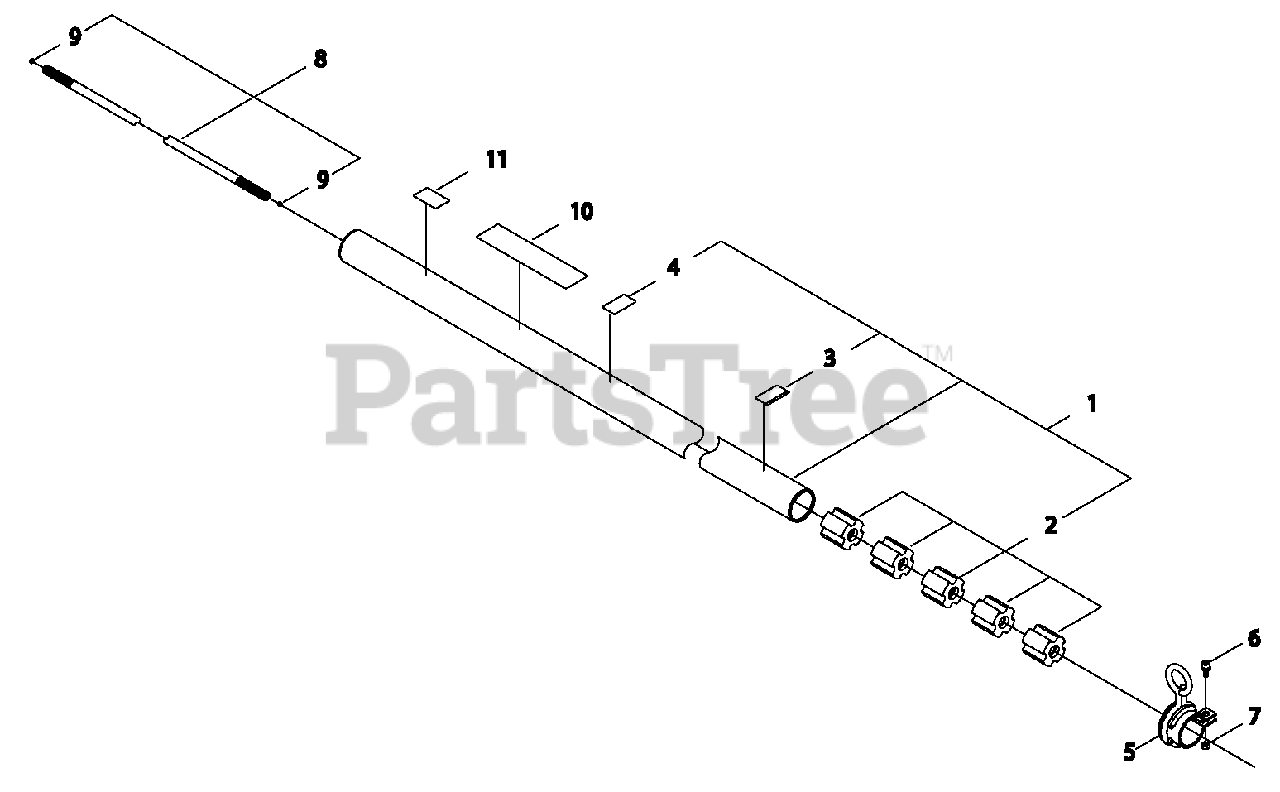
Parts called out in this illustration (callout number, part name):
1	MAIN PIPE ASSY
2	BUSHING
3	LABEL - ALIGNMENT
4	LABEL - HANDLE LOCATION
5	HANGER ASSY
6	SCREW - 5X12
7	NUT - 5
8	DRIVESHAFT ASSY
9	STOPPER
10	LABEL - CAUTION
11	LABEL - CAUTION
